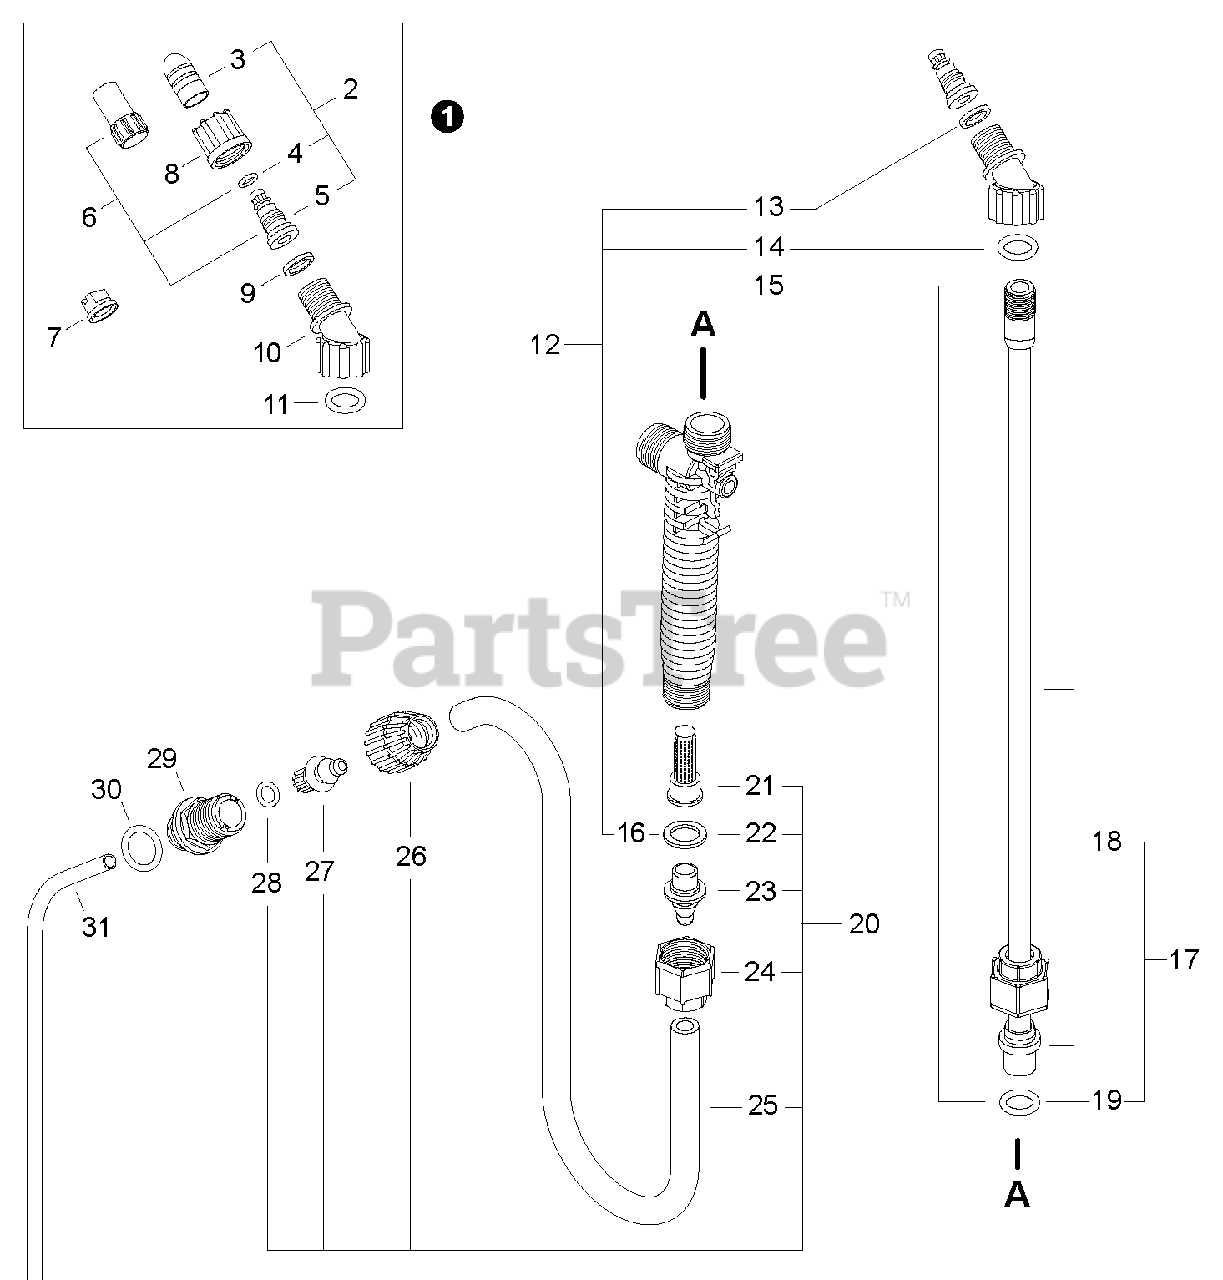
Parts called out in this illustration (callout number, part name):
1	NOZZLE KIT
2	NOZZLE KIT - BRASS
3	CAP, NOZZLE - BRASS
4	O-RING
5	BODY, NOZZLE
6	NOZZLE KIT - PLASTIC
7	NOZZLE - FLAT FAN
8	NUT, NOZZLE
9	GASKET, NOZZLE
10	ELBOW, NOZZLE
11	O-RING
12	WAND GASKET KIT
13	GASKET, NOZZLE
14	O-RING
15	O-RING
16	GASKET, ADAPTER
17	SPRAY WAND ASSY
18	WAND, SPRAYER
19	O-RING
20	HOSE KIT
21	FILTER, SPRAY GUN
22	GASKET, ADAPTER
23	ADAPTER, HOSE - BLACK
24	NUT, HOSE
25	HOSE - 1210mm -- BLACK
26	NUT, TANK
27	ADAPTER, HOSE - WHITE
28	O-RING
29	OUTLET, TANK - 15/16
30	O-RING
31	TUBE, OUTLET 16-1/4"
32	FILTER, OUTLET
